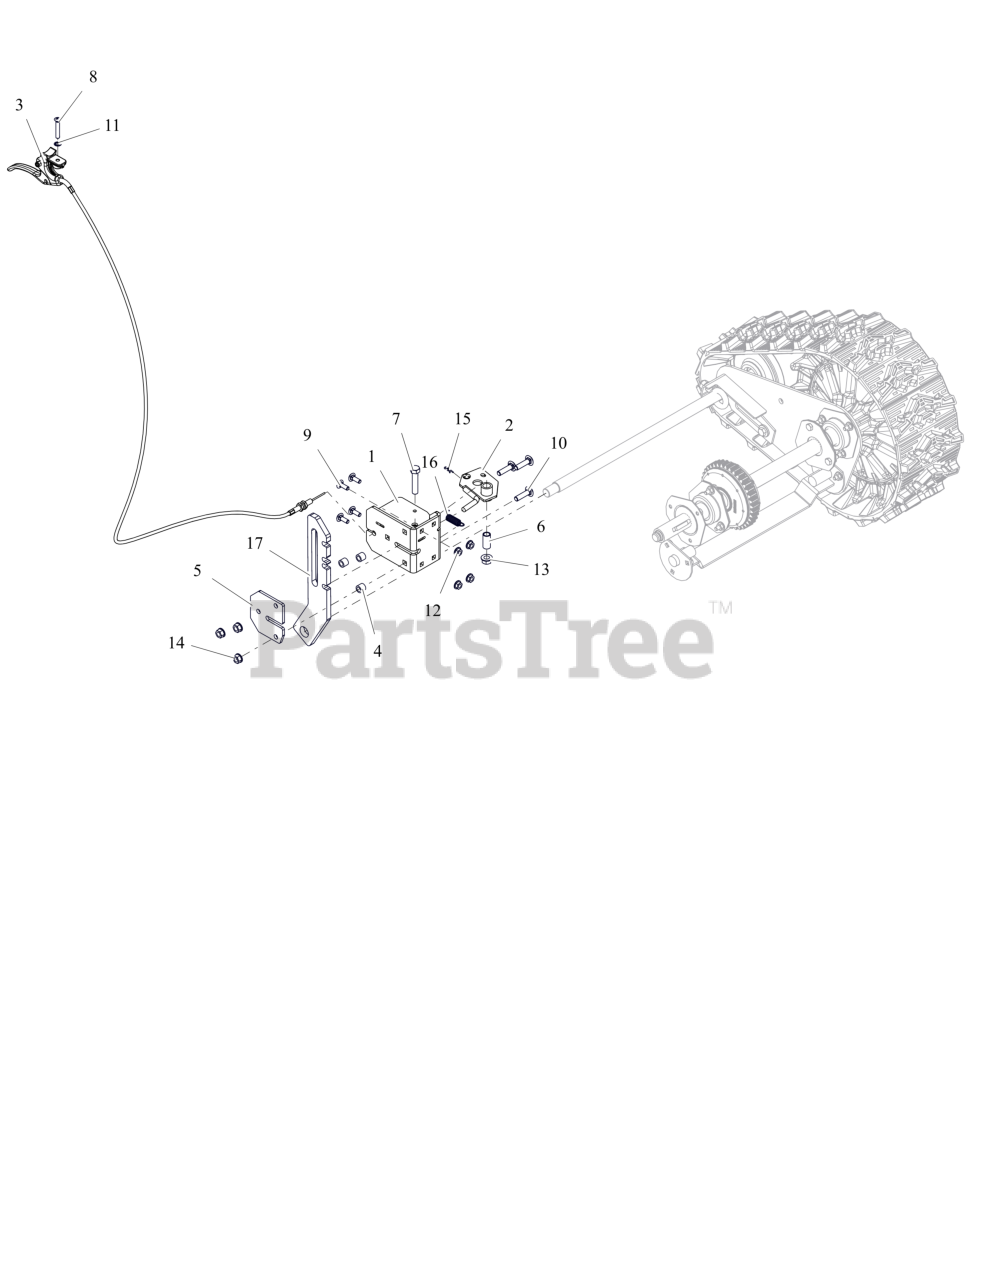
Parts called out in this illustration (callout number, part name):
1	BRACKET, HEIGHT ADJUSTER
2	LOCK,HEIGHT ADJUSTER TRIGGER
3	CABLE, TRACK REMOTE
4	SPACER .50 X .32 X .42
5	PLATE, HEIGHT ADJUSTER
6	BSHG-SLV .385X.500X1.045
7	BLT, HEX .38-16X1.75 G5 ZCC
8	SCR,OVAL .25-20X1.50 ZCC
9	BLT, RHSN .25-20X.750 G5 ZCC
10	BLT, RHSSN.31-18X1.25 G5 ZCC
11	WSHR-LK-INT .250 TH TYA
12	NUT-LK-CTR-FLG .25-20 ZC120
13	NUT-LK-CTR-FLG .375-16 GF ZCC
14	NUT-LK-TOP-FLG .312-18 GF ZCC
15	PIN, HAIR #178 .06X.77 ZCC
16	SPRING-EXT .047 X .438 X 1.85
17	ADJUSTER- HEIGHT-COMPACT BWT
